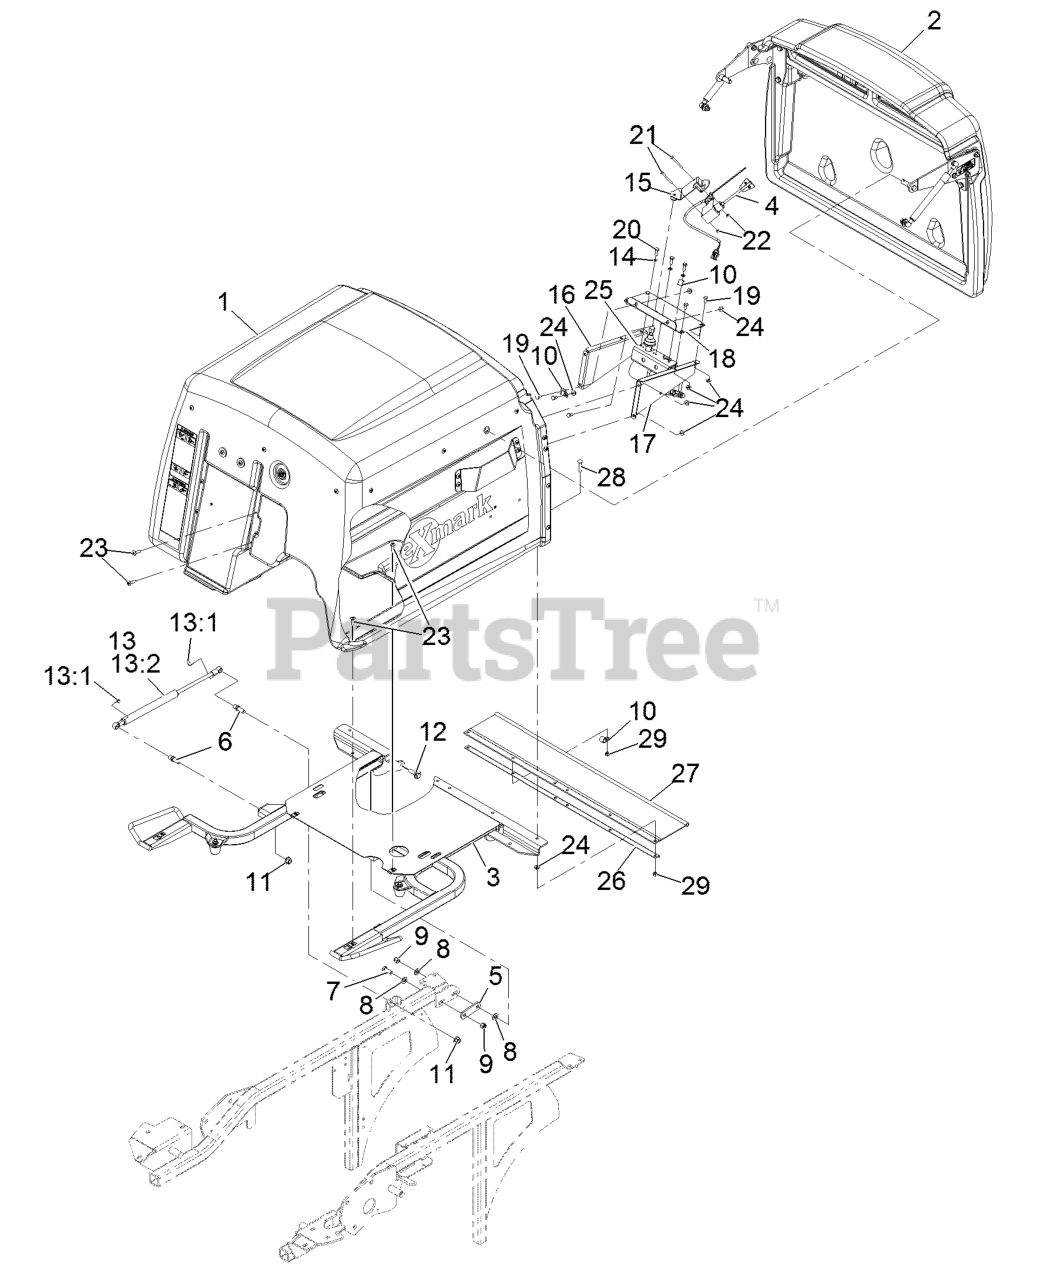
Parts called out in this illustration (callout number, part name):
1	Asm, Hopper
2	Asm, Door Hopper
3	Hopper Frame ASM
4	Asm, Fill Sensor
5	Arm-Lift, Deck
6	Stud-Ball
7	Screw-HH
8	Washer-Flat
9	Nut-Lock, NI
10	Clip-Loom
12	Screw-Shoulder, HWH
13	Damper Kit
13:1	Clip-Retainer
13:2	Shock-Compression, Gas
14	Washer-Spring
15	Mount-Switch
16	Bracket-Drive Motor, LH
17	Bracket-Drive Motor, RH
18	Plate-Switch
19	Screw-HH
20	Screw-HH
21	Screw-PPH
22	Nut-Lock, NI
23	Screw-TTH
26	Channel-Frame, Hopper
27	Deflector-Grass
28	Screw-CARR
29	Nut-Lock, NI
